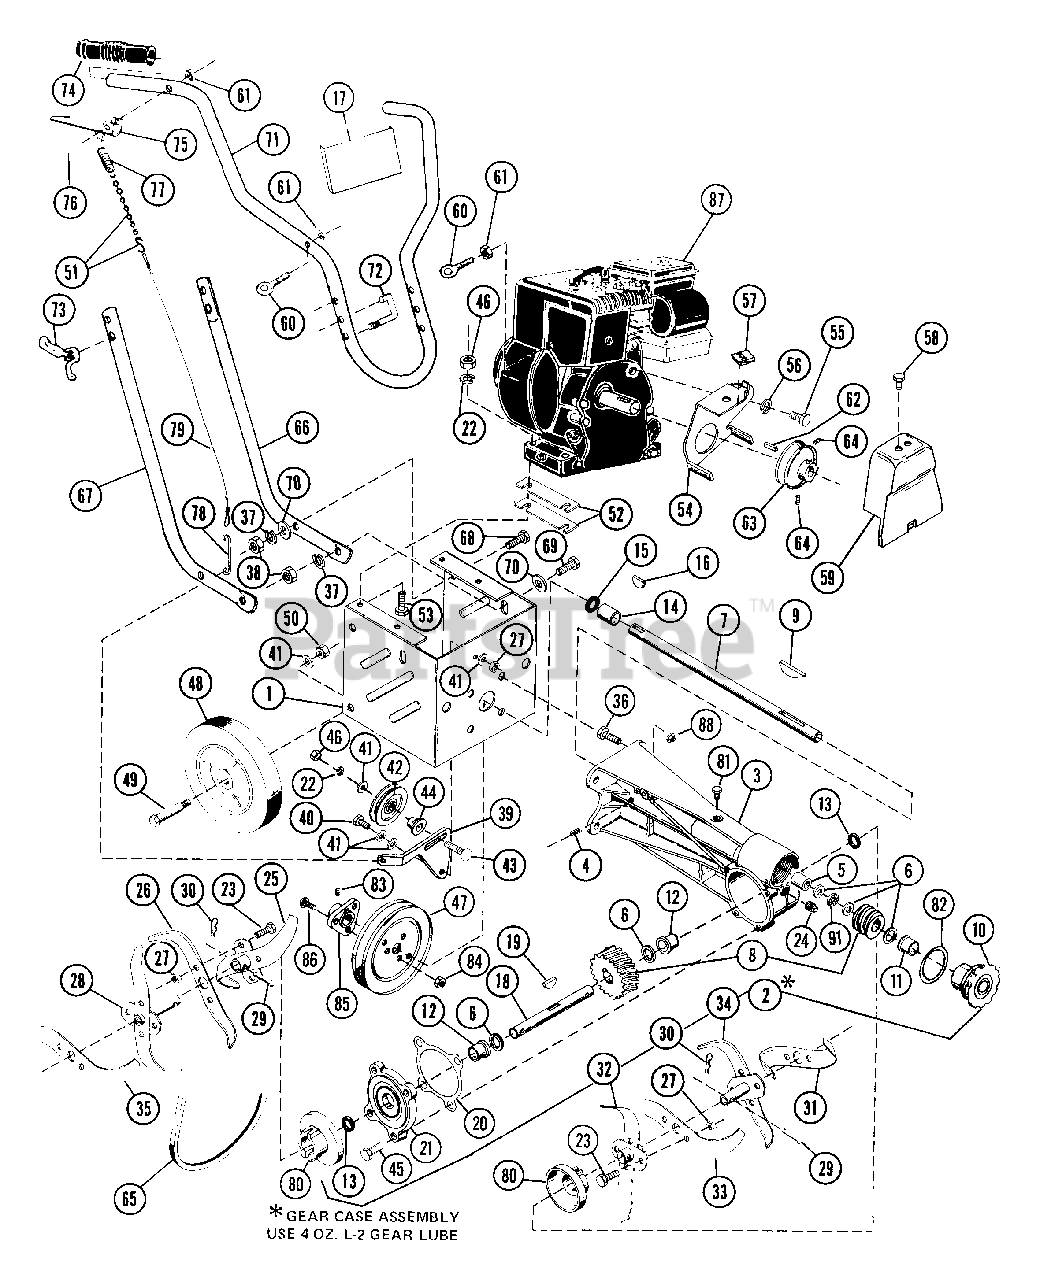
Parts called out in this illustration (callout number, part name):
1	MAIN FRAME
2	GEAR CASE ASSEMBLY
3	GEARCASE - ALUMINUM
4	BREATHER
5	BSHG-SLV .750X1.000X.750
6	WSHR-HDND-THRST .755X1.40X.062
7	WORM SHAFT
8	WORM & GEAR SERVICE ASSEMBLY
9	KEY-FTHR .188X1.38X.188
10	ADJUSTMENT PLUG
11	BSHG-FLG .750X1.000X.750X1.132
12	BSHG-FLG .750X1.250X.750X1.375
13	SEAL .750X1.980X.375
14	BSHG-SLV .750X1.000X1.000
15	SEAL .750X1.000X.125
16	KEY-WDRF .188X.875X.375 SAE11
17	NAME PLATE
18	TINE SHAFT
19	KEY-WDRF .188X.625X.25 SAE 61
22	WSHR-LK .312X.097 PL HVY
23	BLT-HEX .31-18X.75 PL GR2
24	PIPE PLUG
25	R H INNER TINE SPOOL
26	R H INSIDE TINE
27	NUT-LK .312-18 GR A PL
28	R H OUTER TINE SPOOL
29	PIN, CLEVIS .243/.248X1.50 YWZ
30	PIN-HAIR INT .08X.18X1.18
31	R H OUTSIDE TINE
32	L H INNER TINE SPOOL
33	L H INSIDE TINE
34	L H OUTER TINE SPOOL
35	L H OUTSIDE TINE
36	SCREW - FLG WIZ LOCK HH PL
37	WSHR-LK .375X.115 HVY PL
38	NUT-HEX .375-16
39	IDLER BRACKET
40	BLT-HEX .31-18X1.00 PL GR 2
41	WSHR-FL-STL .38X.875X.083 PL
42	IDLER
43	BLT-RDHDSQNK .31-18X1.38SHT PL
44	SPCR, BRG .315X.50X.688X.281
45	BLT-SERHFWH .31-18X.62 PL
46	NUT-HEX .312-18
49	SHOULDER BOLT
50	NUT-LK-CTR .375-16 GR A PL
51	CHAIN & CONNECTOR
52	SHIM
53	BLT-HEX .31-18X1.75 PL GR2
54	BELT FINGER & COVER BRACKET
55	BLT-HEX .75-16X2.50 PL GR5
56	WSHR-LK .500X.151 HVY PL
57	NUT-SPEED U-TYPE .312-18
58	BLT-HEX .31-18X.50 PL GR2
59	BELT COVER
60	ROD HANGER EYEBOLT
61	NUT-LK-CTR .250-20 PL
62	KEY-SQ .188X1.0X.188 SAE 8630
63	ENGINE SHEAVE
64	SET SCREW
65	V-BELT, 4L-RAW EDGE
66	L H LOWER HANDLEBAR
67	R H LOWER HANDLEBAR
68	BLT-HEX .38-16X1.75 PL GR2
69	BLT-HEX .38-16X1.00 PL
70	WSHR-FL-STL.406X.812X.065PL
71	UPPER HANDLEBAR
73	WING NUT, .312-18
74	GRIP
75	CLUTCH HANDLE
76	BLT-HEX .25-20X1.50 PL GR5
77	SG-TENS .092X.69X1.75 WLD 54
79	CLUTCH CABLE
80	DUST CAP
81	BLT-SCRHFWH .38-16X.50 PL
83	SCR-SET .25-20X.25 SKHCUP OH
84	NUT-FLG. .312-18 PL
85	HUB
86	BLT-SERRDHD SL .31-18X.75 YZ
88	NUT-LK-FLG .375-16 PL
91	BRG-N THRST .754X1.24X.078
